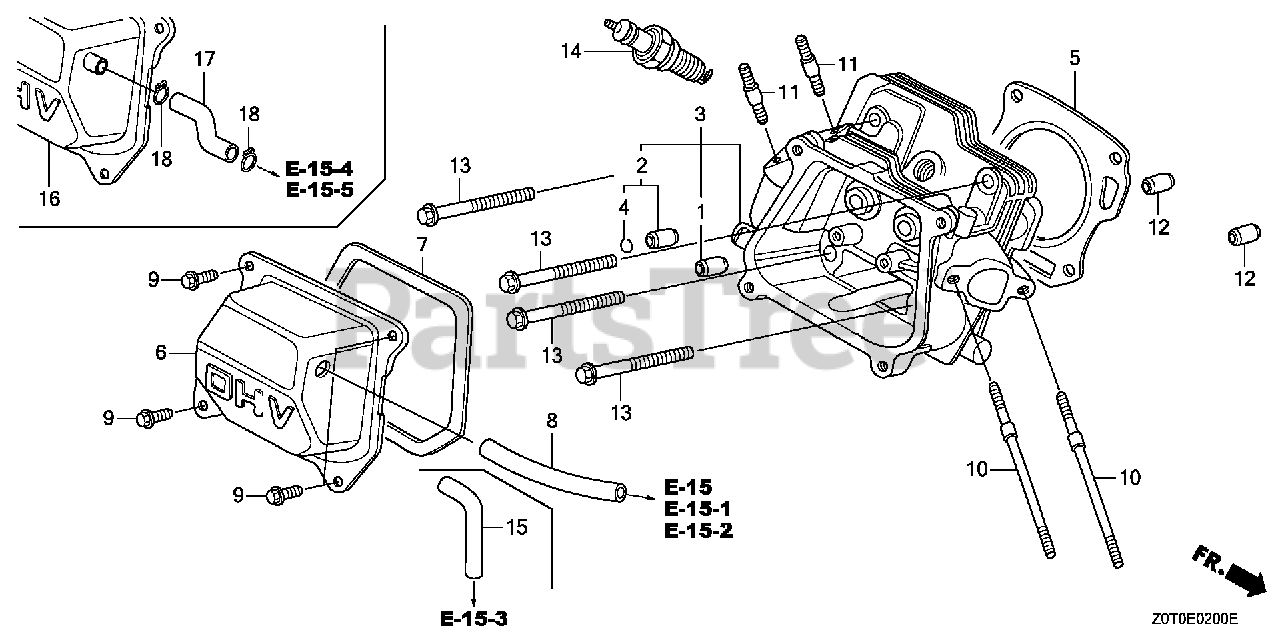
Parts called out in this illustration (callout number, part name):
3	CYLINDER HEAD
5	GASKET, CYLINDER HEAD (NIPPON LEAKLESS)
6	COVER, HEAD
7	GASKET, CYLINDER HEAD COVER
7	GASKET, HEAD COVER
8	TUBE, BREATHER
9	BOLT, FLANGE (6X12) (CT200)
10	BOLT, STUD (6X109)
11	BOLT, STUD (8X32)
12	PIN A, DOWEL (10X16)
13	BOLT, FLANGE (8X60)
14	SPARK PLUG (BPR5ES) (NGK)
14	SPARK PLUG (BPR6ES) (NGK)
14	SPARK PLUG (W16EPR-U) (DENSO)
14	SPARK PLUG (W20EPR-U) (DENSO)
